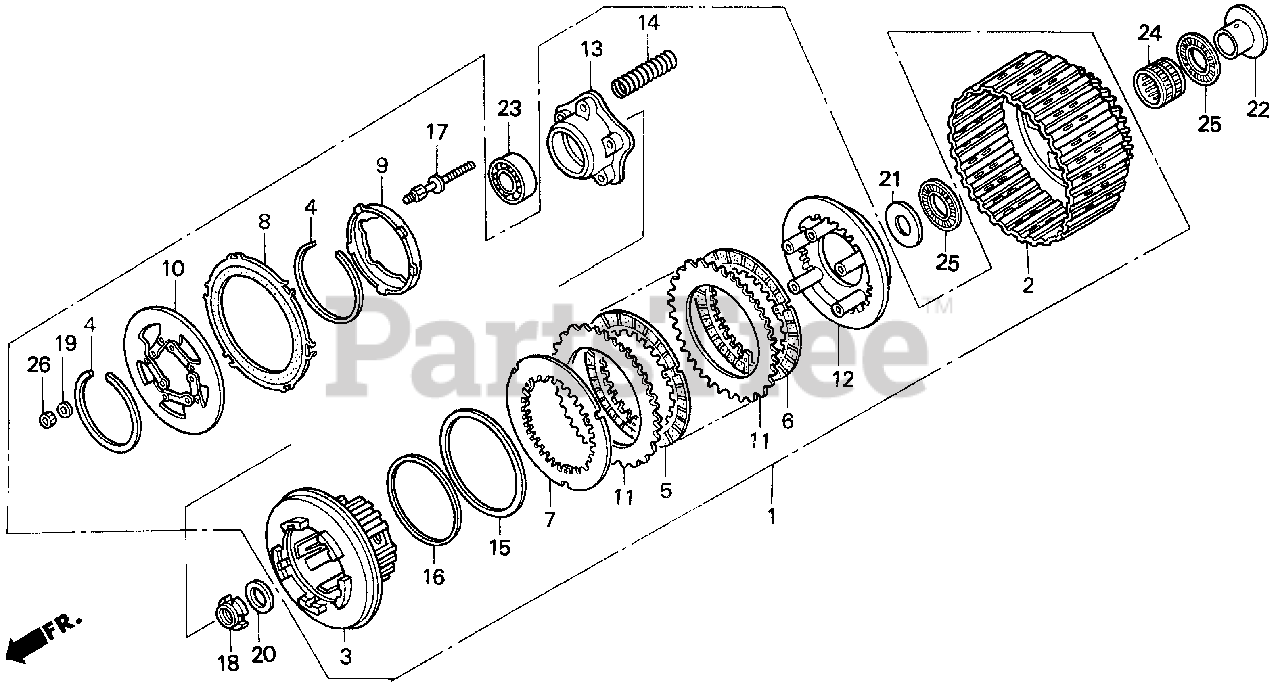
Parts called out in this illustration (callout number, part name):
1	CLUTCH ASSY.
2	CLUTCH (OUTER)
3	CENTER, CLUTCH
4	SET-RING (100.5MM)
5	DISK A, CLUTCH FRICTION
6	DISK A, CLUTCH FRICTION
7	DISK B, CLUTCH FRICTION
8	PLATE B, BRAKE
9	PLATE, OIL FENCE
10	PLATE C, BRAKE
11	PLATE, CLUTCH
12	PLATE, CLUTCH PRESSURE
13	PLATE, CLUTCH LIFTER
14	SPRING, CLUTCH
15	SPRING, CONED DISK
16	SEAT, SPRING
17	BOLT, SPECIAL (6X28)
18	NUT, LOCK (20MM)
19	WASHER (10MM)
20	WASHER, LOCK
21	WASHER, THRUST (23X42X3)
22	COLLAR (25X30X30)
23	BEARING, BALL (6905)
24	BEARING, NEEDLE (32X37X26)
25	BEARING, NEEDLE (32X47X2)
26	NUT, HEX. (5MM)
